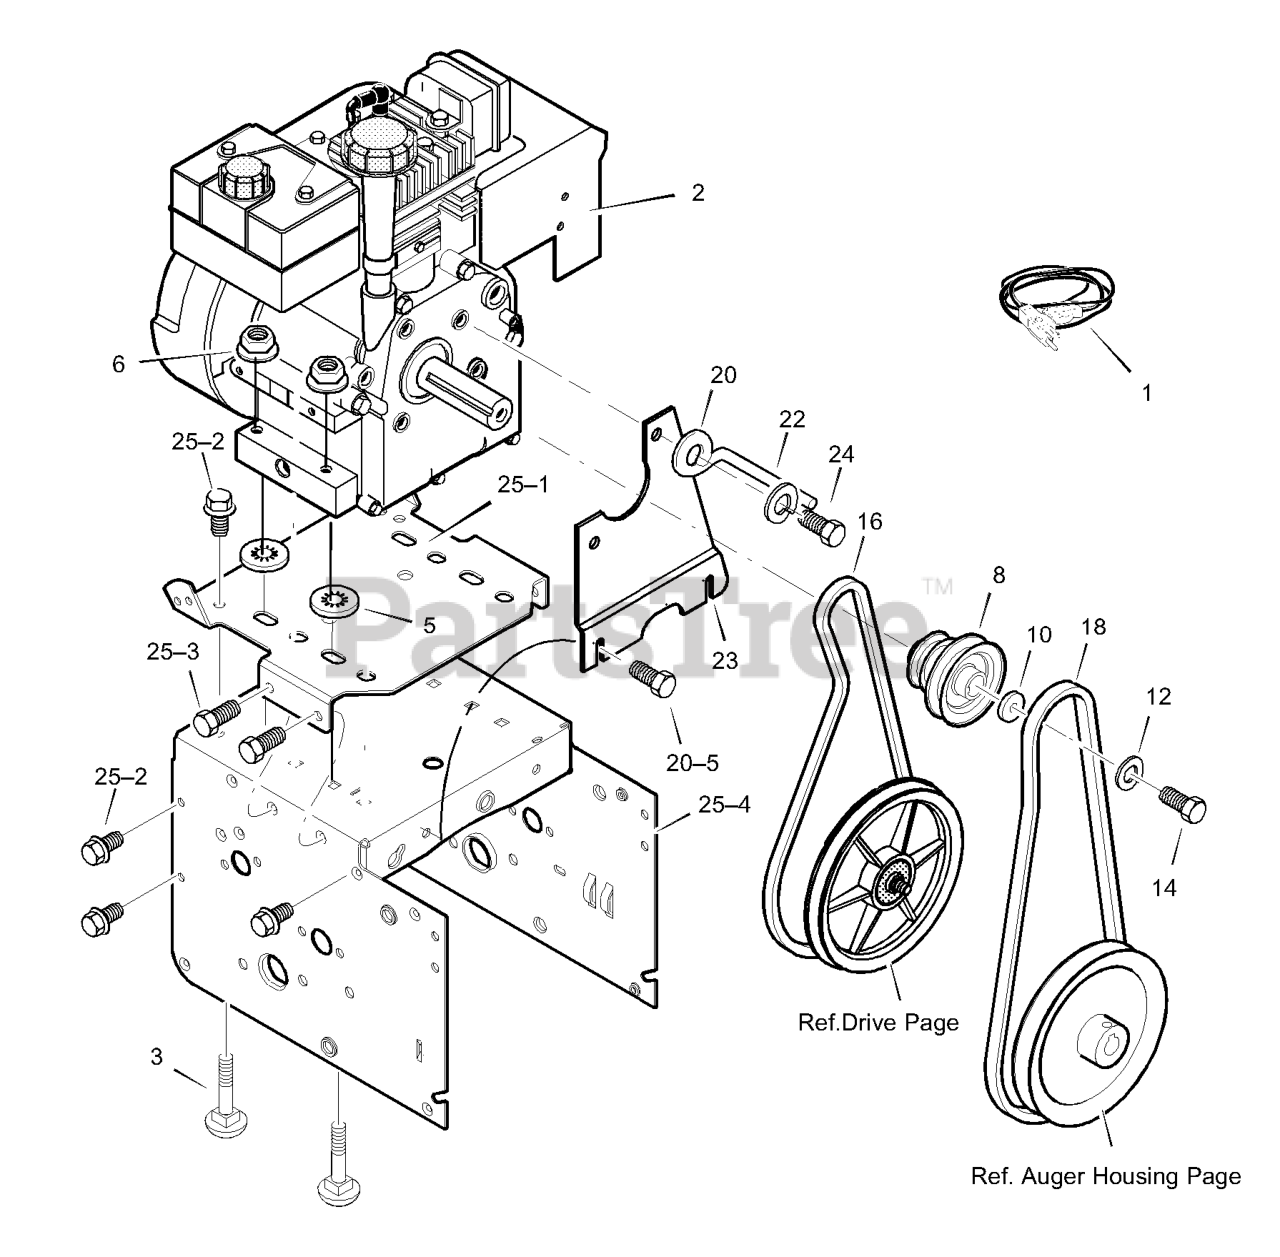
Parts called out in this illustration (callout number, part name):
1	CORD, Electric, 10FT. 110V
2	ENGINE
3	BOLT, CARRIAGE 5/16-18
5	RETAINER, PUSH
6	NUT, HEX 5/16-18
8	PULLEY, ENGINE
10	WASHER
12	WASHER .38ID
14	SCREW, 3/8-24 x 1.00
16	BELT, V 3L 33.13LG
18	BELT, V 4L 38.1MF16" 5-10
20	GUIDE, BELT
22	WASHER, SPTLK .31X.58X.08
23	PLATE, ANTI VIBRATION
24	SCREW, 5/16-24 x 1.00
25	FRAME ASSEMBLY
25-1	PLATE, ENGINE MOUNT
25-2	SCREW, TAP 1/4-20 X .63
25-3	SCREW, TAP 5/16-18 X .50
25-4	FRAME, MOTOR BOX
